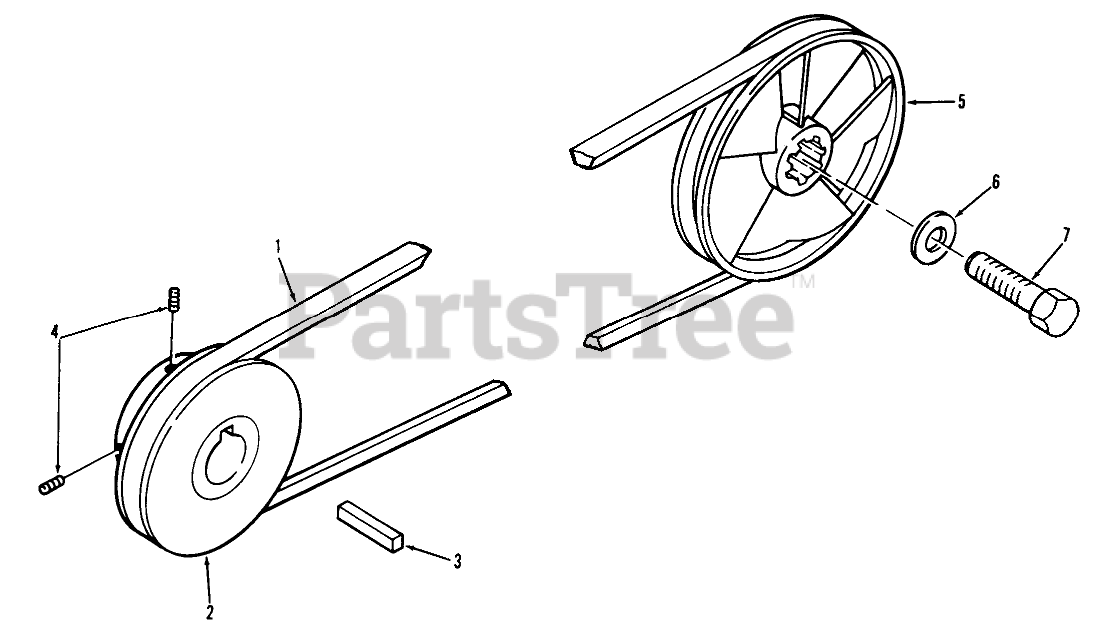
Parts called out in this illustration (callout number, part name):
1	V BELT
2	PULLEY
4	Set Screw
5	PULLEY
6	WASHER
7	Bolt
